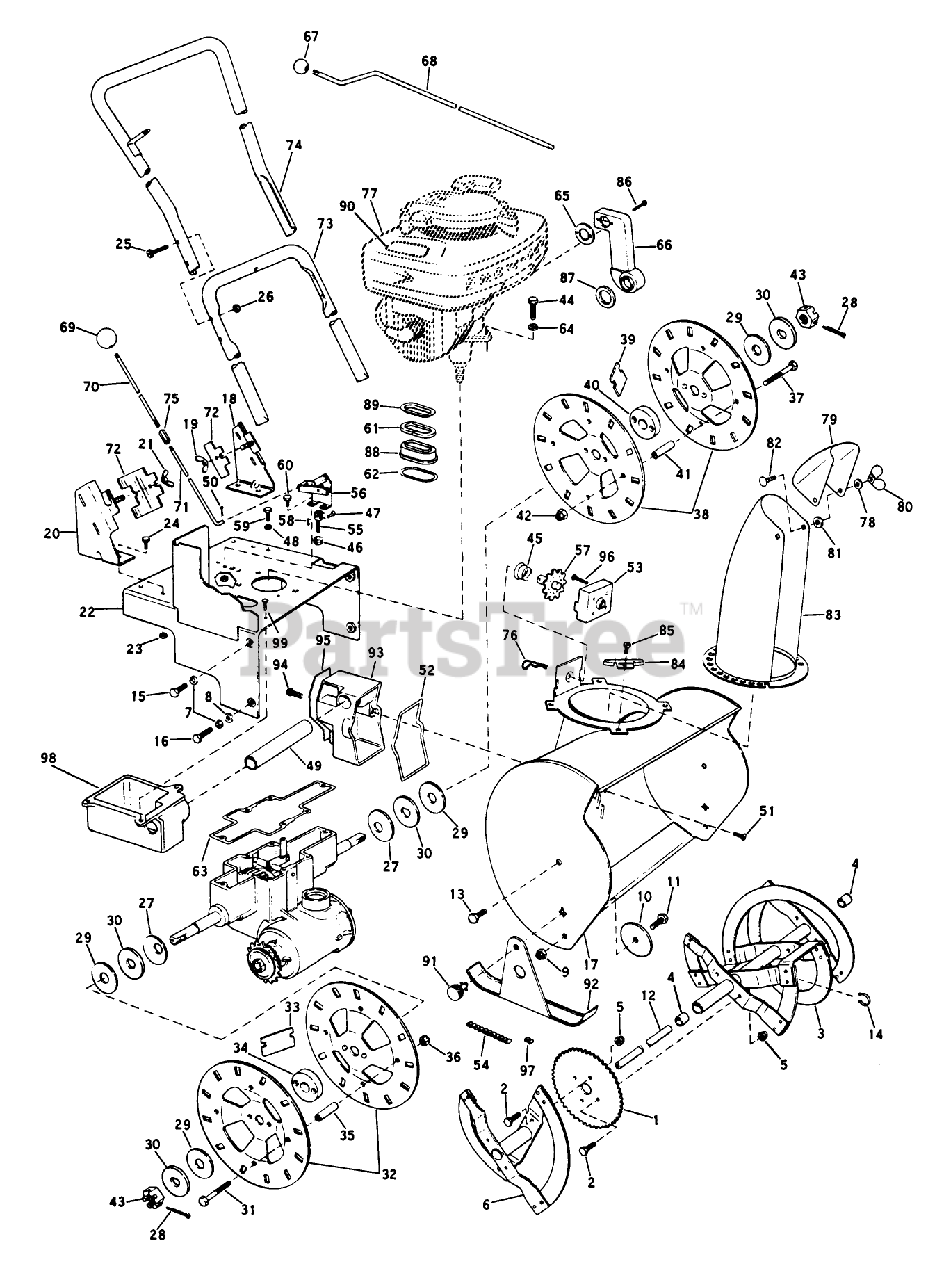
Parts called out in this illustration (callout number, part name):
1	Sprocket-Impeller Shaft
3	Impeller Assy.
4	Bushing
5	Nut-Huglok
7	Lockwasher-Screw-Hsg. to Base
11	Stud-Front Wheel
13	Screw-Impeller Shaft to Housing
15	Screw-Housing to Base
16	Screw-Housing to Base
24	Screw-Guard to Housing
26	STOP NUT
28	Cotter Pin-Wheel
30	Washer-Steel
43	Nut-Wheel Mtg.
46	Grommet-Base
51	Screw-Muffler to Housing
52	Gasket-Muffler to Housing
54	Drive Chain
62	Gasket-Exhaust
83	Chute Flange Assy.
85	Screw-Chute Retainer
90	4301 24 LB MOWER OM
96	Drive Screw
